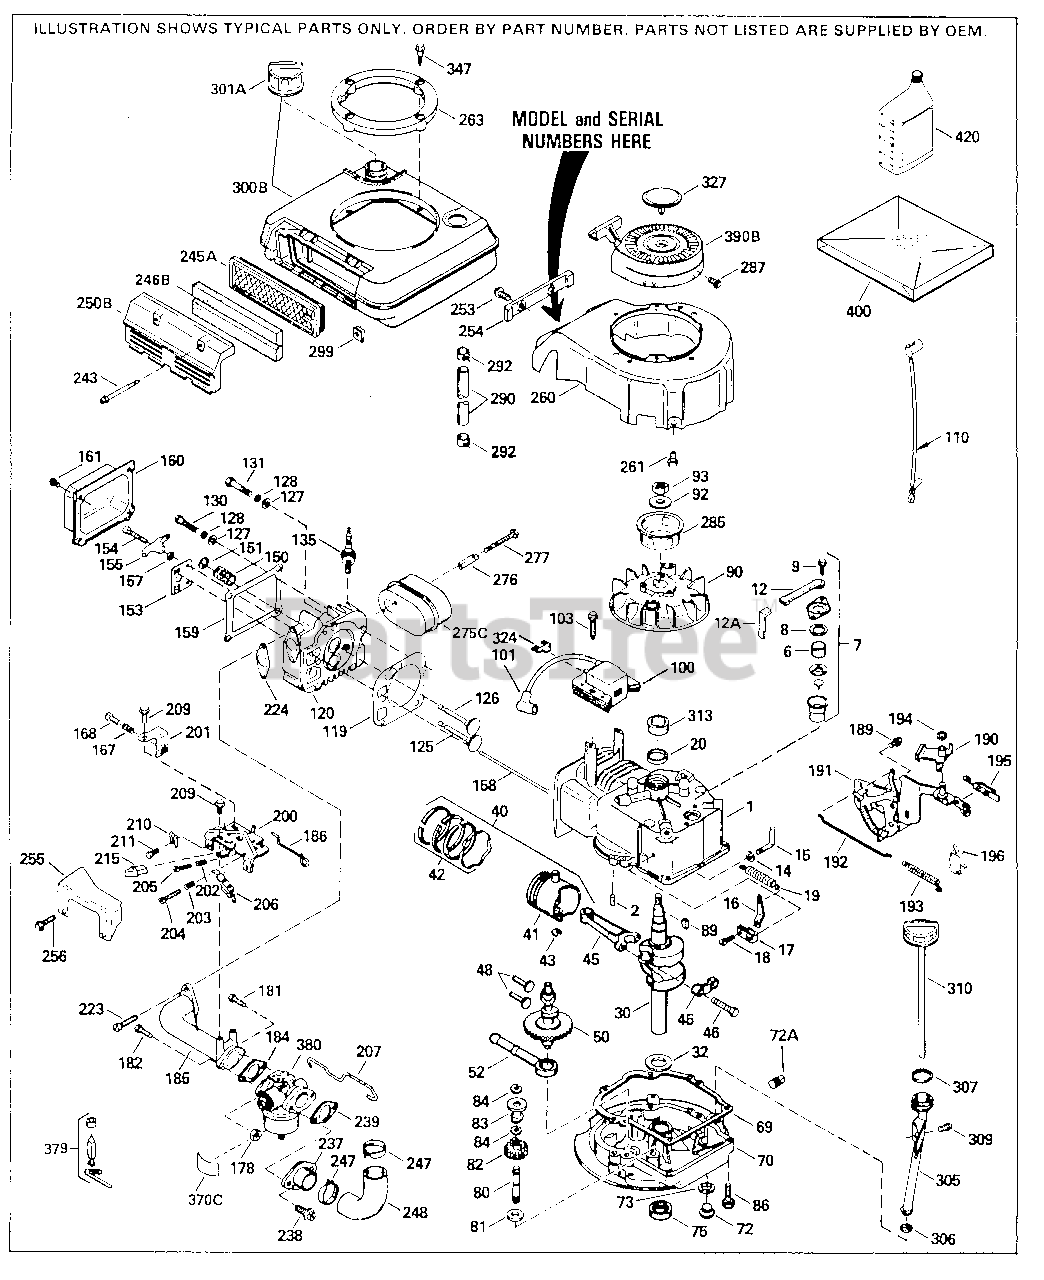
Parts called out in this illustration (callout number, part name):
1	"Cylinder (Incl. 2 & 20) (2-1/2" Bore)
2	Dowel Pin
6	Element, Breather
7	Breather Assy. Incl. 6, 8, 9, 12 & 12 A
8	* Gasket, Breather
9	Screw, 10-24 x 9/16"
12	Tube, Breather
14	Flat Washer
15	Rod, Governor (Incl. 14)
16	Lever, Governor
17	Clamp, Governor lever
18	Screw, 8-32 x 5/16"
19	Spring, Governor
20	Seal, Oil
30	Crankshaft
40	Piston, Pin & Ring Set (Std.) 2-1/2" Bore
40	Piston, Pin & Ring Set (.010" OS)
40	Piston, Pin & Ring Set (.020" OS)
41	Piston & Pin Ass'y. (Std.) (Incl. 43) (2-1/2")
41	Piston & Pin Ass'y. (.010" OS) Incl. 43
41	Piston & Pin Ass'y. (.020" OS) Incl. 43
42	Ring Set (Std.)
42	Ring Set (.010" OS)
42	Ring Set (.020" OS)
43	Piston Pin Retaining Ring
45	Rod Assy., Connecting (Incl. 46)
46	Bolt, Connecting rod
48	Valve Lifter
50	Camshaft (MCR)
52	Oil Pump Ass'y.
69	* Gasket, Mounting flange
70	Mounting Flange (Incl. 72, 75 & 80)
72	Plug, Oil drain (Incl. 73)
73	* Drain Plug Gasket Do not use w/plast ic plug
75	Oil Seal
80	Shaft, Governor
81	Washer, Flat
82	Gear Assy., Governor (Incl. 81)
83	Spool, Governor
84	Retaining Ring
86	Screw, 1/4-20 x 1-1/4"
89	Flywheel Key (also available in Packa ged Part #740007B)
90	Flywheel
92	Washer, Belleville
93	Nut, Flywheel
100	Solid State Assy.
101	Cover, Spark Plug
103	Screw, Torx T-15, 10-24 x 1"
110	Ground Wire
119	* Gasket, Cylinder head
120	Head Cylinder
125	Exhaust Valve (Std.) (Incl. 151)
125	Exhaust Valve (1/32" OS) (Incl. 151)
126	Intake Valve (Std.) (Incl. 151)
126	Intake Valve (1/32" OS) (Incl. 151)
127	Washer, Flat
128	Washer, Belleville
130	Screw, 5/16-18 x 1-1/2"
135	Resistor Spark Plug (RN4C) also avail able in Packaged Part #740069
150	Spring, Valve
151	Cap, Valve spring keeper
153	Guide, Push rod
154	Stud, Rocker arm
155	Arm, Rocker
157	Nut, Hex jam, 1/4-28
158	Rod, Push
159	* Gasket, Rocker arm cover
160	Rocker Arm Cover (Chrome)
178	Nut & Lock Washer 1/4-28
181	Screw, 1/4-28 x 7/8"
182	Screw, 1/4-28 x 7/8"
184	* Gasket, Carburetor
185	Pipe, Intake
186	Link, Governor spring
189	Screw, 1/4-20 x 3/8"
190	Lever, Brake
191	Bracket, S.E. Brake (Incl. 195)
192	Link, Control
193	Spring, Extension
194	Ring, Retaining
195	Terminal Assy.
200	Control Bracket (Incl. 202 thru 206)
202	Spring, Compression
203	Spring, Compression
204	Screw, 5-40 x 7/16"
205	Screw, 6-32 x 21/32"
207	Link, Throttle
209	Screw, 10-24 x 9/16"
210	Conduit Clip
211	Screw, 10-32 x 3/8"
223	Screw, 1/4-20 x 1"
224	* Gasket, Intake pipe
237	Adapter, Air cleaner
238	Screw, 10-32 x 7/16"
239	* Gasket, Air cleaner
243	Screw, 10-32 x 2-3/32"
245A	Air Filter (also available in Package d Part #740013B)
246B	Air Filter (also available in Package d Part #740013B)
247	Clamp, Air cleaner
248	Tube, Air cleaner
250B	Cover, Air cleaner
253	Screw, 10-32 x 1/2"
254	Cover, Blower housing
260	Housing, Blower
261	Screw, 1/4-20 x 15/32"
263	Ring, Shroud
276	Plate, Lock
277	Screw, 5/16-18 x 2-1/2"
285	Hub, Starter
287	Screw, 8-32 x 1/2"
290	Line, Fuel (Braided 16")(40 cm)
292	Fuel Line Clamp
299	Clip, "U" Type nut, 10-32
300B	Shroud & Tank Assy. (Incl. 299 & 301)
301A	Fuel Cap (Red)
305	Oil Fill Tube
306	* Gasket, Fill tube
307	"O" Ring
309	Screw, 10-32 x 1/2"
310	Dipstick
313	Spacer, Flywheel
327	Starter Plug
347	Screw, 10-32 x 27/32"
370C	Decal, Primer
379	Inlet, Needle, Seat & Clip Assy.
380	Carburetor (Incl. 184) (Refer to Divi sion 5, Section A, page A6-4 or Fiche 11, Grid F-3for breakdown)
390B	Rewind Starter Refer to Division 5, S ection C, page 34 or Fiche 11, Grid G -3 for breakdown
400	Gasket Set (Incl. items marked*)
420	SAE 30, 4-Cycle Engine Oil (Quart)
